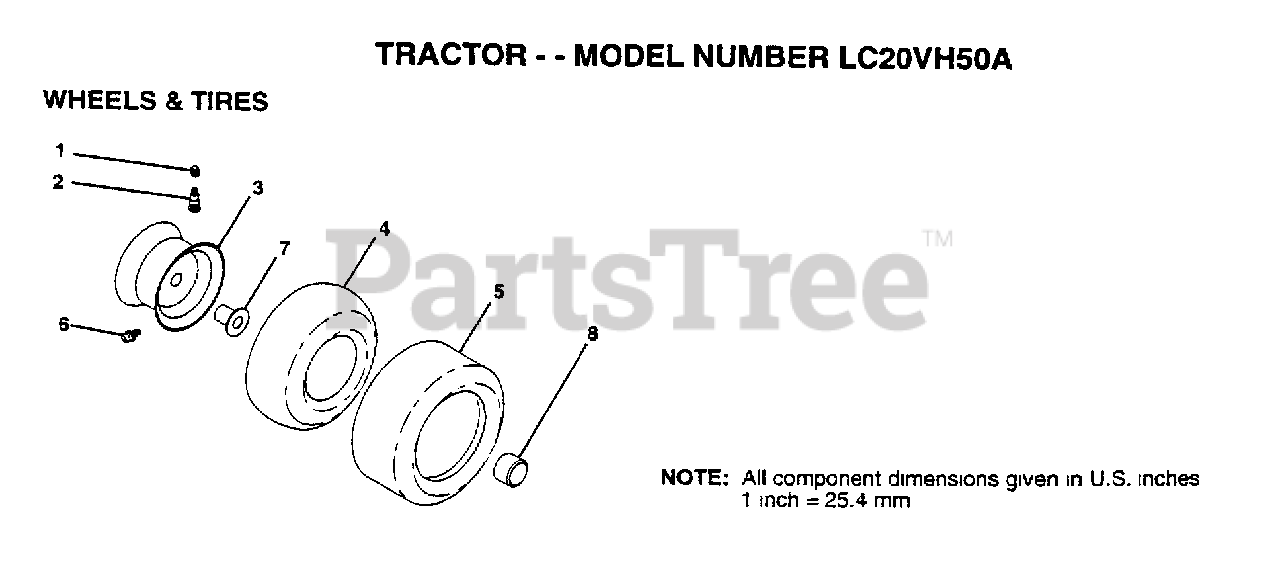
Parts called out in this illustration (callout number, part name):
1	VALVE CAP
2	VALVE STEM LT
3	RIM.FRONT.
3A	"WHEEL,REAR"
4	TUBE.16X6.5/7.5-8
4A	TUBE.23X8/10-12
6	ZERK FITTING M
6A	FITTING LT
7	"FLANGE, BEARING"
8	HUB CAP
